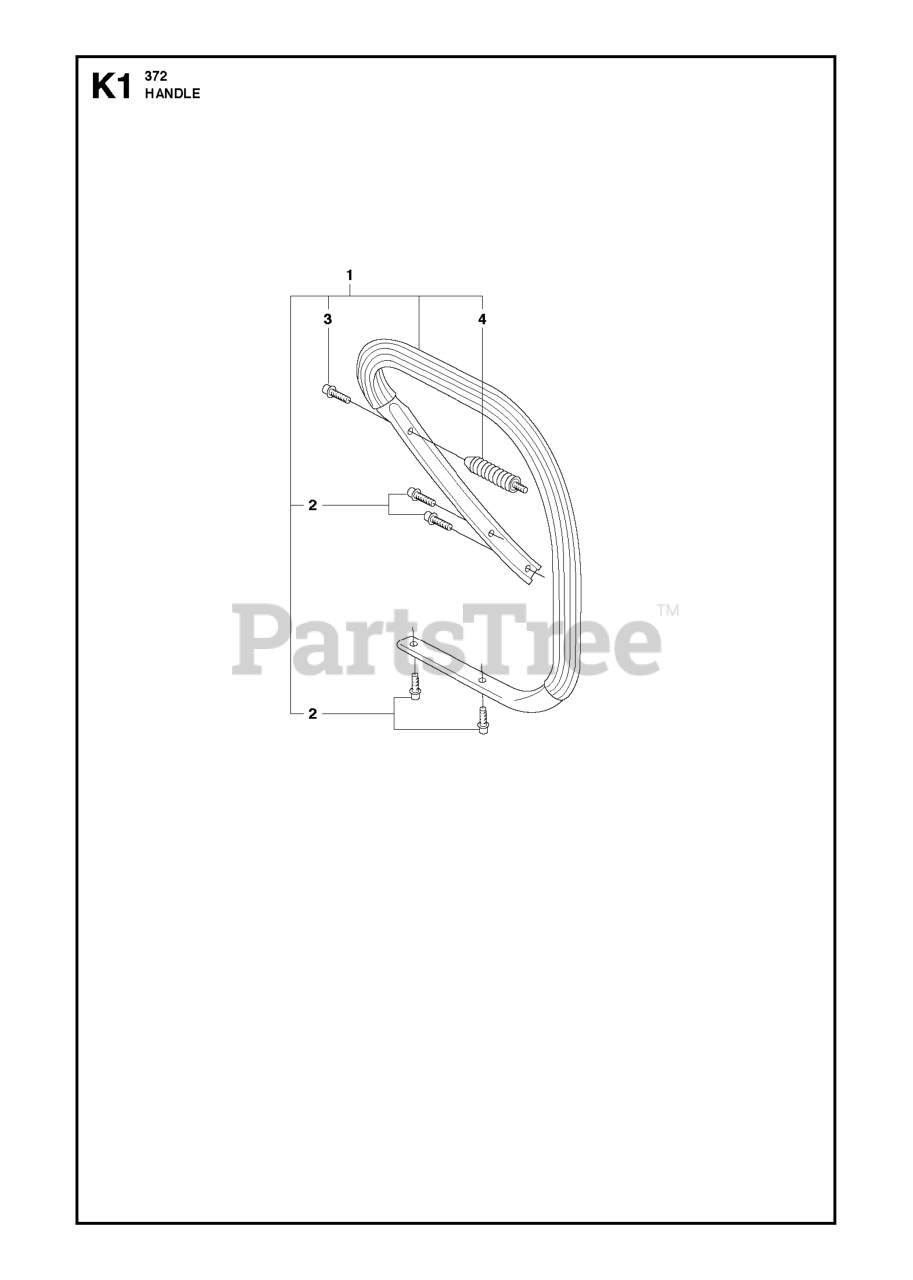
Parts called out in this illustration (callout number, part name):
1	FRONT HANDLE
2	SCREW ITXSCFT PW5.5X16 T27 8.
3	SCREW ITXSCFT PW6.3X22 T27 8.
4	VIBRATION ISOLATOR
4	ANTIVIBRATION ELEMENT
